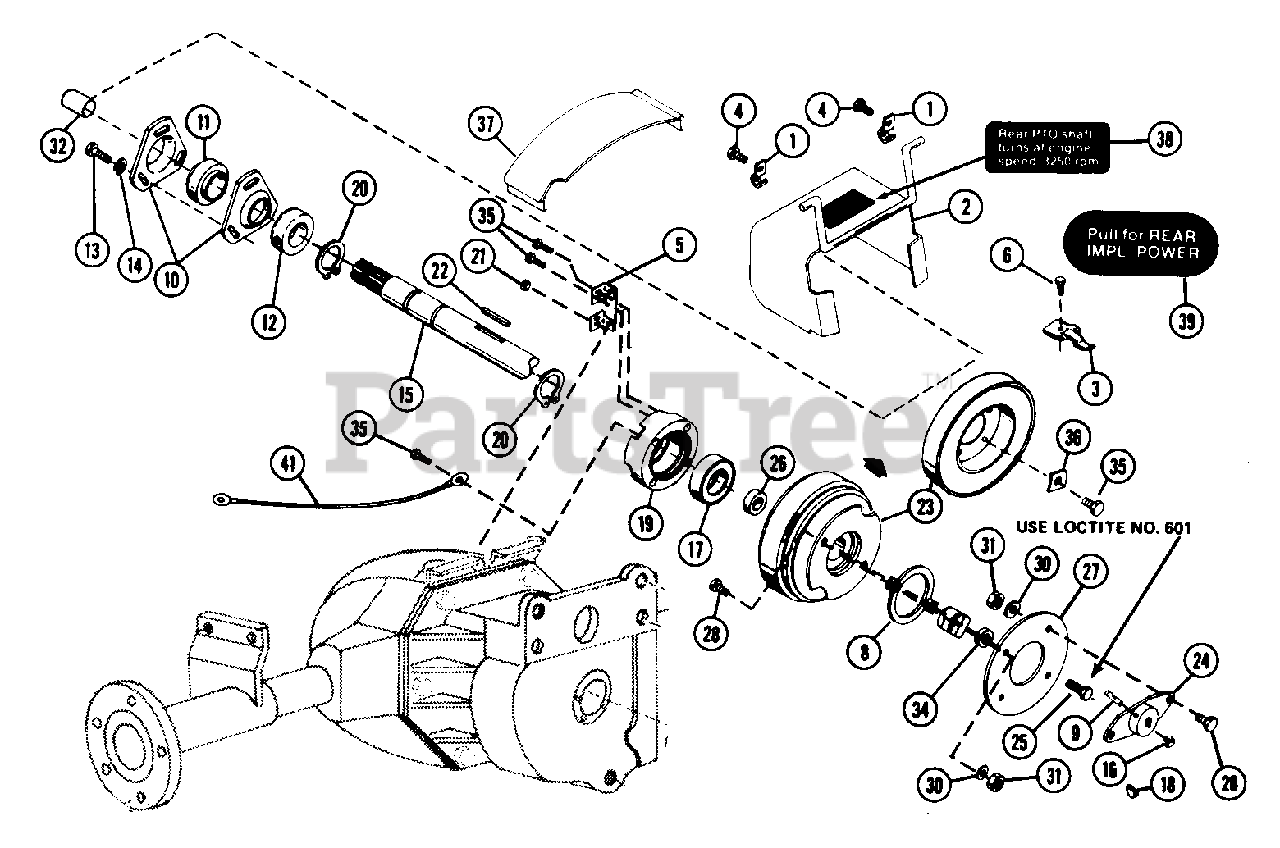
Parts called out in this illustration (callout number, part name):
2	PTO SHIELD
3	SNAP FASTENER
4	SCR-TAP .250-20X.50 HXSLHDPL
5	TORQUE BRACKET ASSEMBLY
6	SCR-TAP 10-24X.375 HWH PL TR
8	PILOT PLATE
9	LOCK STUD
10	BEARING FLANGE
11	BRG/W COLLAR 1.0 X 2.047 X.844
12	BEARING COLLAR
13	BLT-HEX .31-18X.75 PL GR2
14	WSHR-LK .312X.097 PL HVY
16	NUT-LK TOP .375-16 GR C YWZC
17	BRG-BALL 1.0X2.0X.56
18	KEY-WDRF .188X.75X.313 SAE 9
19	BEARING MOUNT
20	RG-RTNG-EXT 1.00X.078
21	NUT-LK-CTR .312-24 PL
22	KEY-SQ .25X1.0X.25 SAE 8630
23	ELECTRIC CLUTCH
24	COUPLING
25	BLT-BTHD .38-16X1.25 GR5
26	SPACER 1.006X1.438X.306
27	SPACER COUPLING
28	BLT-HEX .31-18X.75 PL GR2
30	WSHR-FL-STL.344X.688X.065PL
31	NUT-LK .312-18 GR A PL
32	SHAFT COVER
34	RETAINER
35	SCR-TAP 10-24X.75 T-PH PL TR
36	RETAINER CLIP
38	REAR PTO DECAL - 3200 RPM
39	REAR IMPLEMENT DECAL
41	GROUND WIRE
42	CLUTCH SWITCH
44	CLUTCH HARNESS
